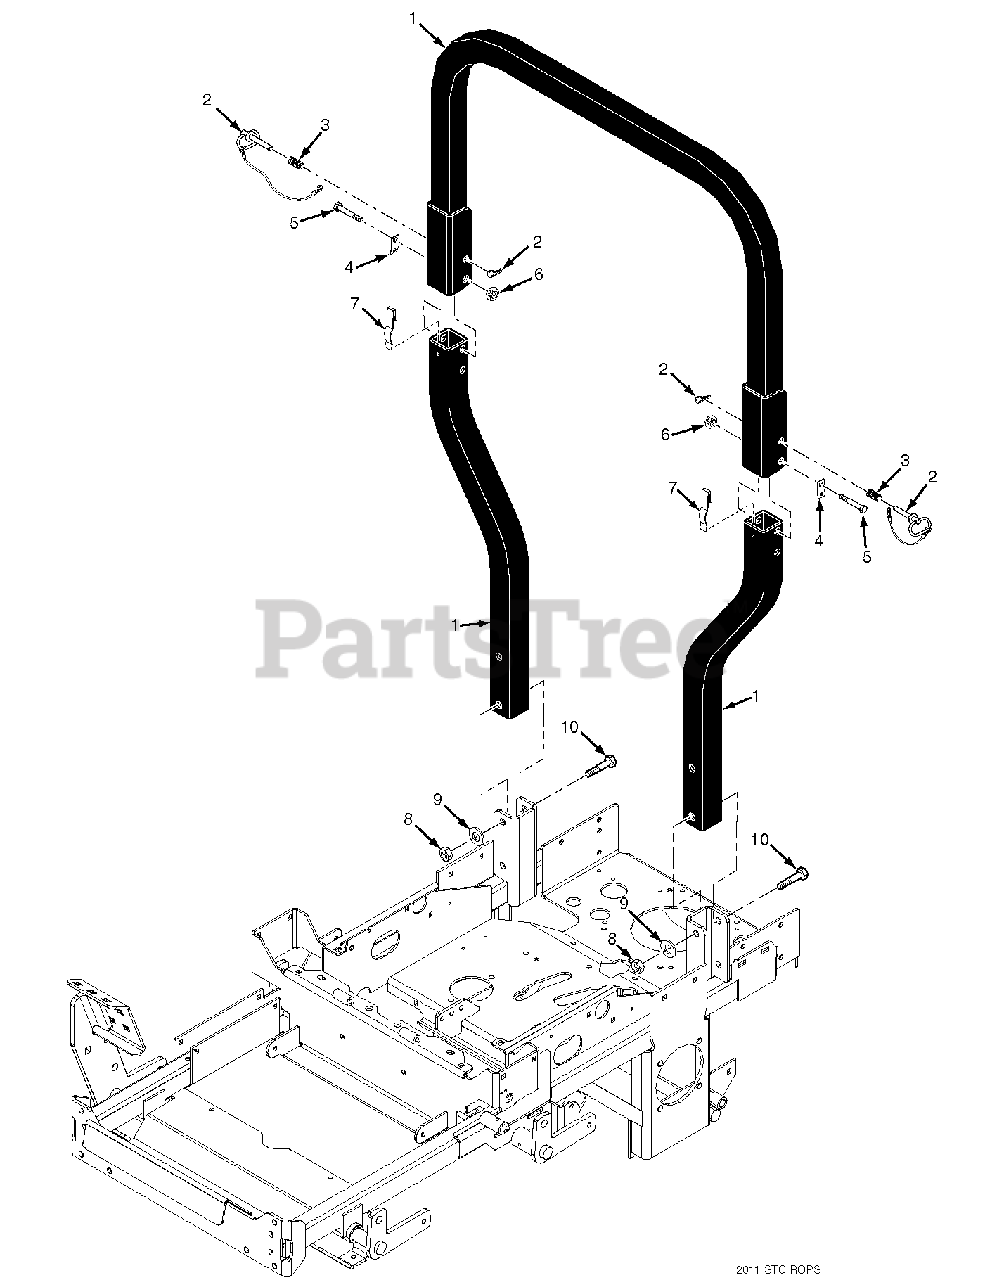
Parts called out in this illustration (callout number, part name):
1	STC Foldable ROPS
2	Pin Assembly
3	Spring, ROPS
4	Clip, ROPS
5	Bolt, Hex Head 1/2-13 x 3-1/4"
6	Nut, Center Lock 1/2-13
7	Spring Clip, ROPS
8	Nut, Center Lock 1/2-13
9	Flatwasher, 1/2-.562 x 1.375 x .109
10	Bolt, Hex Head 1/2-13 x 3-1/2"
